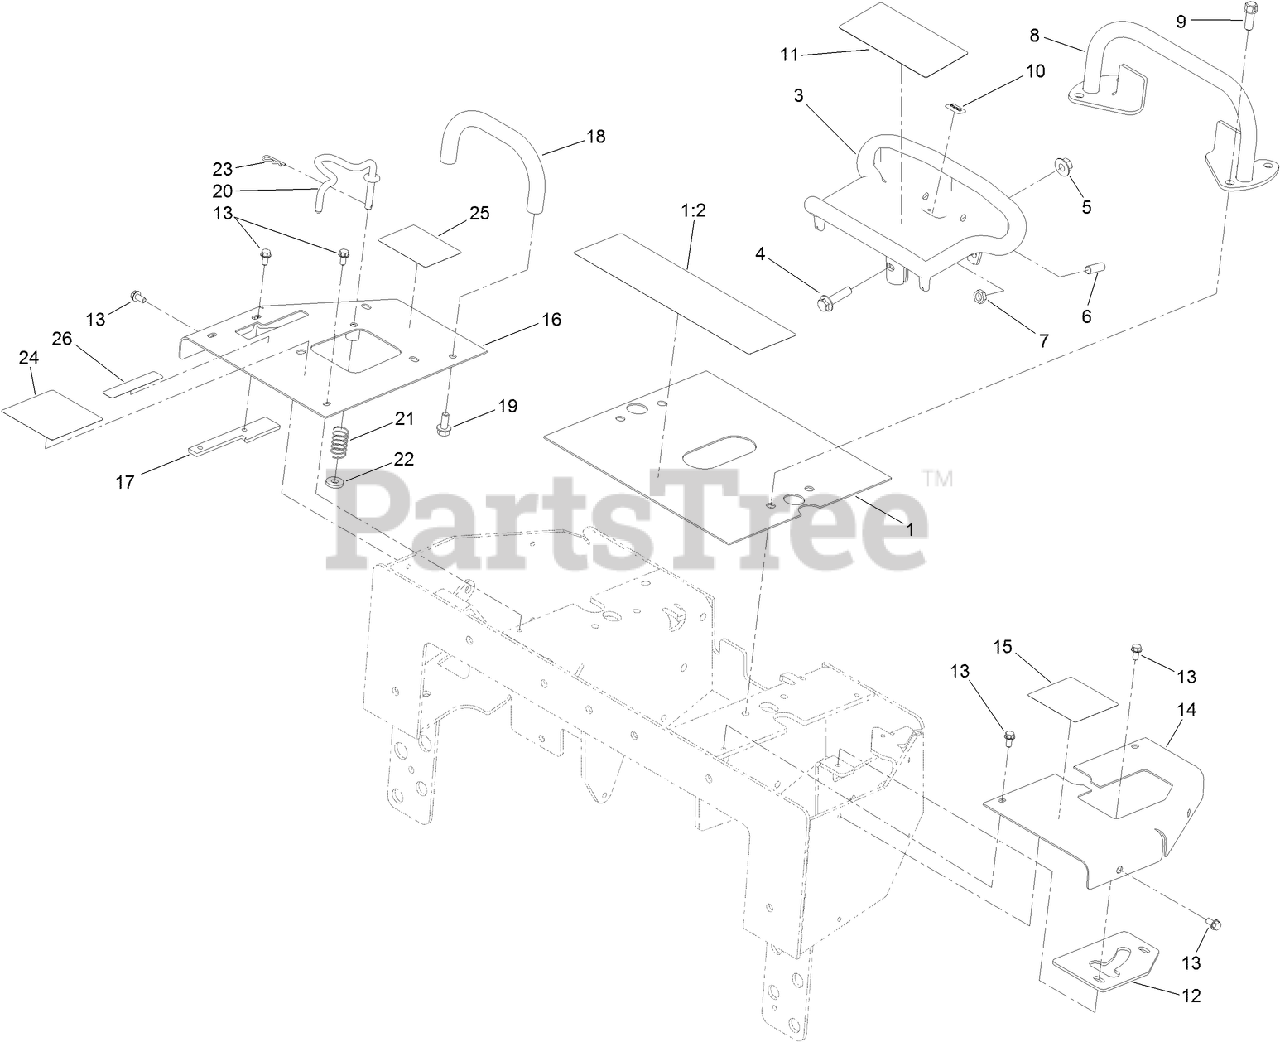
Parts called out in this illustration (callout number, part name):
1	CENTER PANEL ASM
1:2	DECAL-DANGER
3	HANDLE-CONTROL
4	SCREW-HHF
5	NUT-FLANGE
6	SCREW-SET
7	NUT-JAM
8	BAR-REFERENCE
9	SCREW-TAPTITE
10	DECAL
11	DECAL-TRACTION
12	PLATE-STOP
13	SCREW-HWH
14	PANEL-LH
15	DECAL-CONTROL, AUXILIARY
16	PANEL-RH
17	PLATE-LOCKING, BRAKE
18	BAR-REFERENCE
19	SCREW-HHF
20	ROD-INTERLOCK
21	SPRING-CONTROL
22	WASHER-FLAT
24	DECAL-CONTROL, LOADER
25	DECAL-LOADER LOCK
26	DECAL-BRAKE
